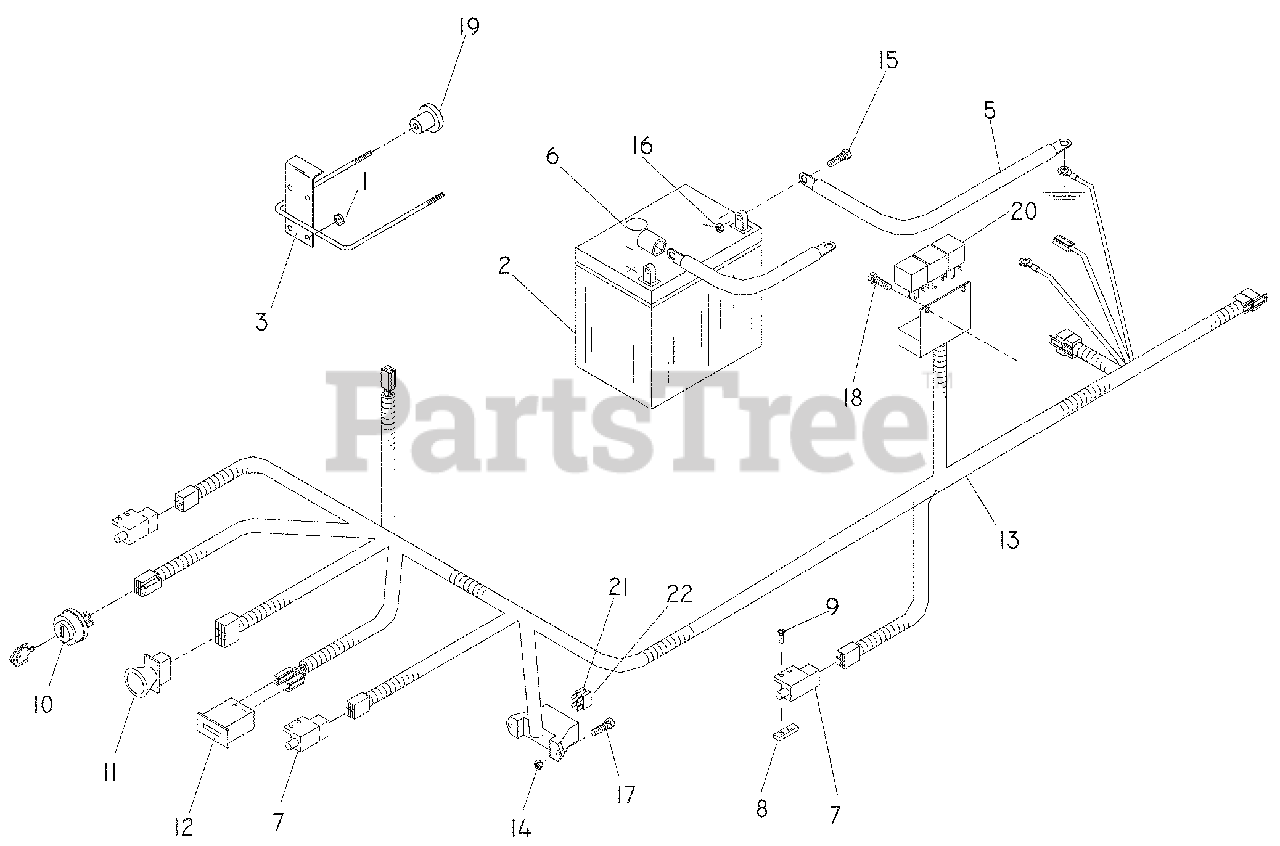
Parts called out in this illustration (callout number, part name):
2	BATTERY, DRY
3	BATTERY HOLD DOWN
4	CABLE, POSITIVE
5	CABLE, NEGATIVE
7	SWITCH, INTERLOCK
8	SCREW PLATE
9	SCREW, 10-24 x 5/8
10	SWITCH, IGNITION
11	SWITCH, BLADE
12	METER, HOUR
13	HARNESS, FRAME
14	NUT 10-24, NYLOC
15	HCS, 5/16 -18 X ¾
16	NUT 5/16-18 HEX NYLOC
17	SCREW, 10-24 x 7/8
18	SCREW, SELF TAPPING
21	FUSE, 7.5 AMP 32V ATO
22	FUSE, 20 AMP, 32V, ATO
